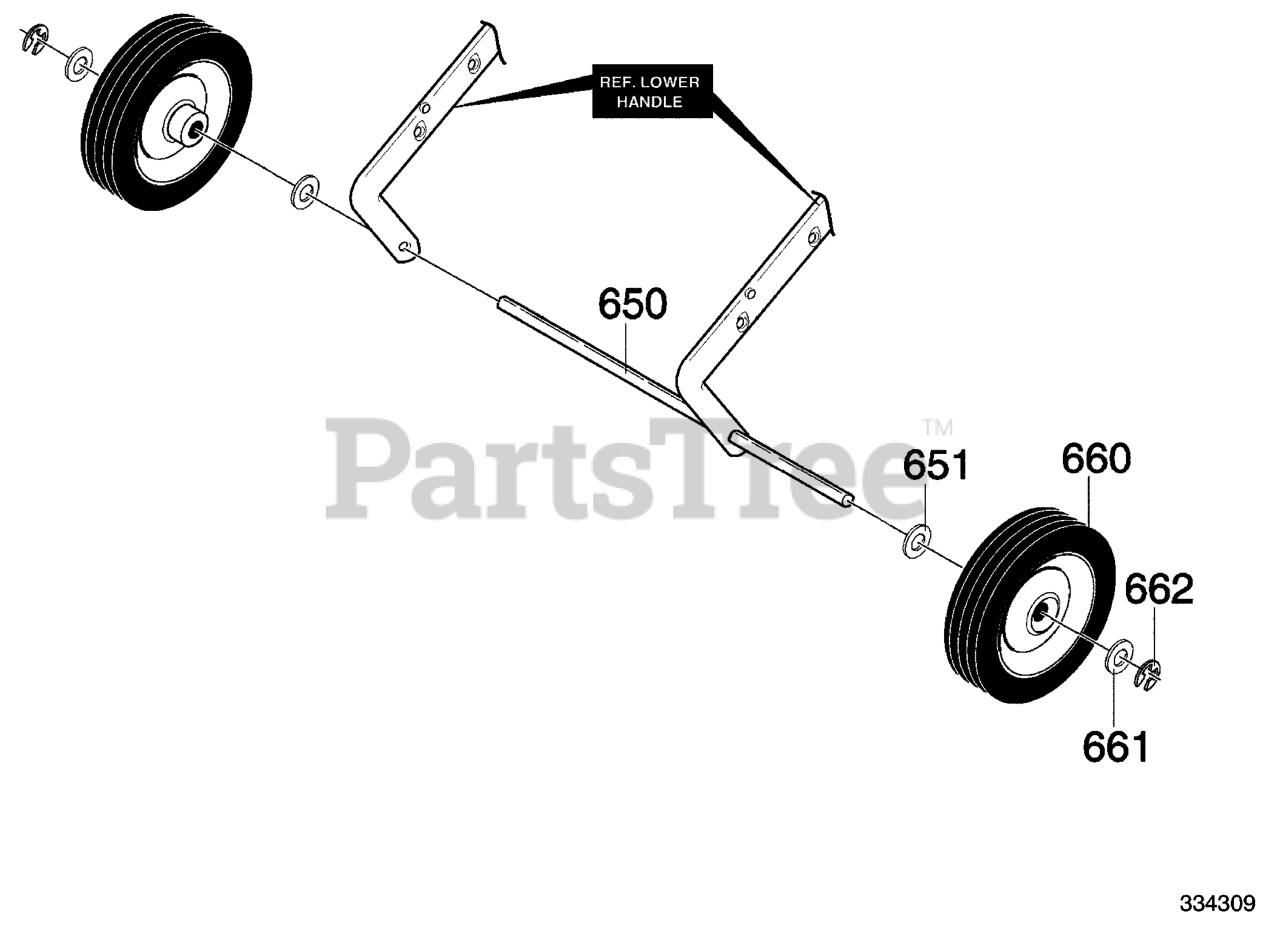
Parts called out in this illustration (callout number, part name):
650	AXLE SHAFT
651	WASHER, FLAT .391X1.00X1.25
660	TIRE & RIM
661	WASHER, FLAT .391X1.00X.125
662	RING, RET E
